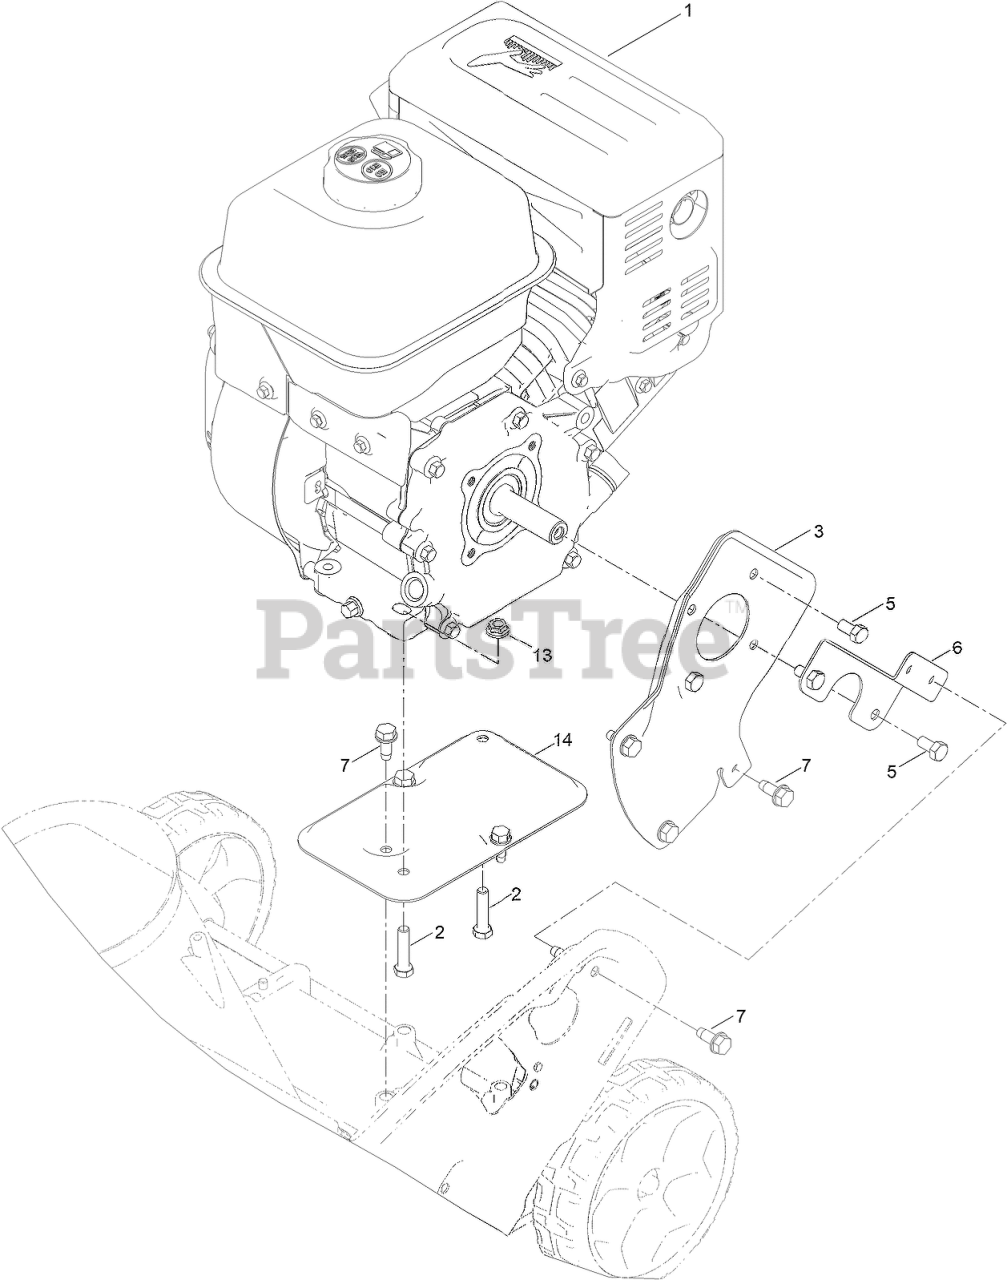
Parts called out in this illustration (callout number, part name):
1	ENGINE - G210FS-4
2	SCREW-HH
3	PLATE-ENGINE, PTO
5	BOLT
6	SUPPORT-ENGINE, SIDE
7	SCREW-THD ROLL, HWH
13	NUT-HF
14	SUPPORT-ENGINE
